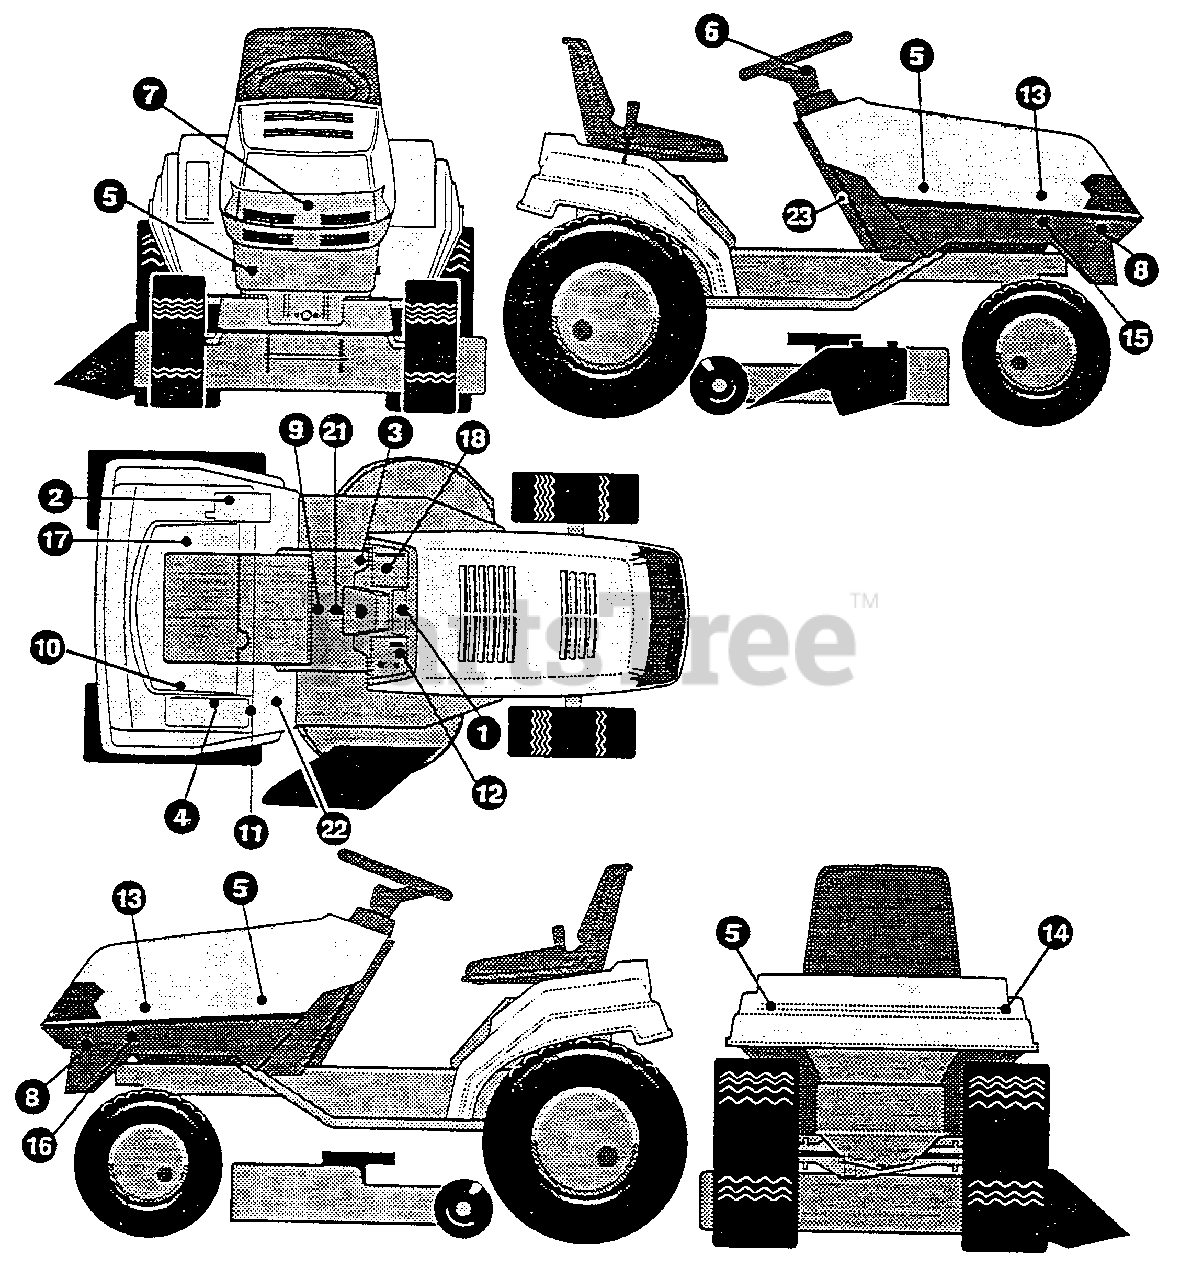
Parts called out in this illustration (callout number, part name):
1	DECAL. DASH CHG,BLK,FUEL,ALL SY
2	DECAL, GEAR SHIFT 6 SPEED ERO
3	DECAL, GEAR SHIFT NEUTRAL ERO
4	DECAL, BLADE CLUT/DECK HGTH ERO
5	DECAL, INSTR FRENCH (CAN) ERO LT
6	DECAL, SHIFT INDICATOR EXPORT
7	DECAL, FENDER REAR,HOOD HUSQ.
8	DECAL, GUNSIGHT CENT. STEER
9	DECAL, GUNSIGHT CLEAR BACK
10	DECAL, WHEEL 4 STEER HUSQ.
11	DECAL, INSTRUC CONSOLE TOP
12	DECAL, 4WS PATENT NO. 5048853
13	DECAL, DEPRESS CL/BRAKE
14	DECAL, DASH RH ISO HR,LG,SW
15	DECAL, SHIFT-N-GO (HUSQ)
16	DECAL, MODEL #4125G
17	DECAL, PIN STRIPE RH
18	DECAL, PIN STRIPE LH
19	DECAL, DASH LEFT ENGLISH/ISO
21	REFERENCE ONLY
22	DECAL, OPER. INSTR. ERO TOP FRAME
23	DECAL, DANGER FR/ENG
24	DECAL, PARK BRAKE EXP
